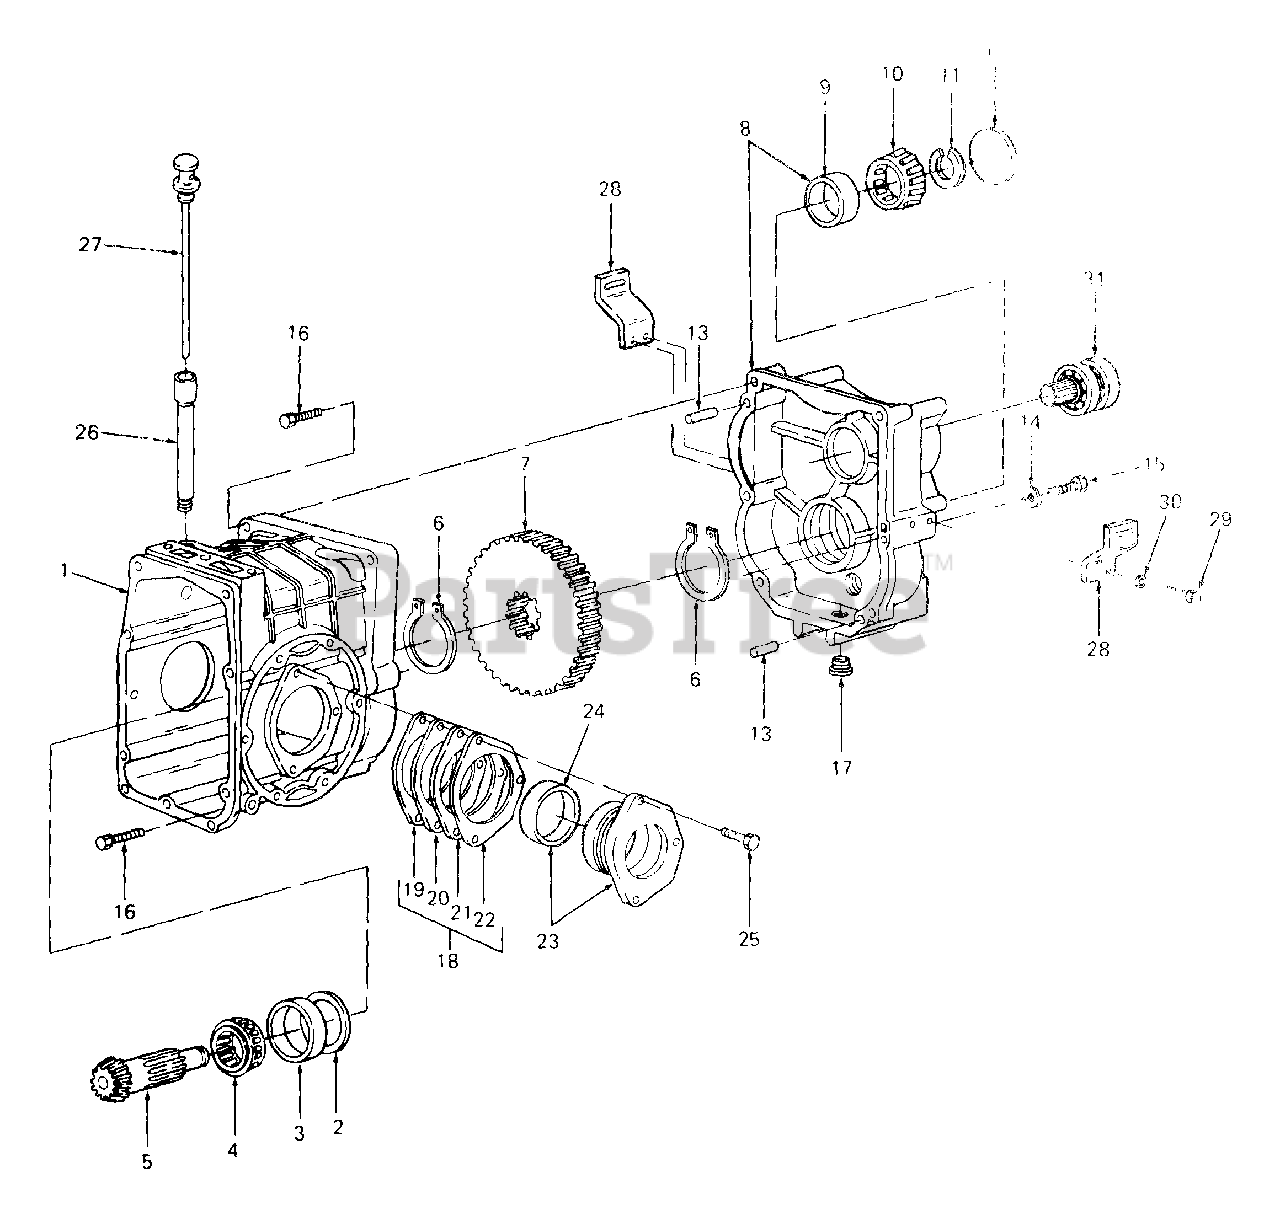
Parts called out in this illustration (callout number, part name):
1	Housing Assy, Rear Transaxle
2	Shim, Rear Bearing Cup, .004 Thk
3	Cup, Roller Bearing
4	Cone, Roller Bearing
5	Shaft, Bevel Pinion
6	Ring, Retaining, 1.312 Dia
7	Gear, Reduction - 71T
8	Adapter Housing Assy
9	Cup, Roller Bearing
10	Cone, Roller Bearing
11	Retainer, Front Bearing, .125 Thk
12	Plug, Expansion, 2.12 OD
13	Pin, Dowel, 3/8 Dia X 5/8 Lg
14	Washer, Spring, .445 X .75 X .017 Thk
15	Screw, Hex Cap, 7/16-14 X 2.75 Lg GR5
16	Bolt, Hex Patch, 7/16-14 X 1.75 Lg GR5
17	Plug, Drain Use Teflon Sealing Tape
18	Shim Package
19	Shim, Bearing Retainer, .004 Thk
20	Shim, Bearing Retainer, .007 Thk
21	Shim, Bearing Retainer, .014 Thk
22	Shim, Bearing Retainer, .028 Thk
23	Retainer Assy, Bearing
24	Cup, Roller Bearing
25	Bolt, Hex Patch, 3/8-16 X 1.0 Lg GR5
26	Tube, Dipstick Use Teflon Sealing Tape
27	Blade Assy, Dipstick
29	Screw, Hex Cap, 3/8-16 X 1.0 Lg GR8
30	Washer, Lock, 3/8
31	Pinion Assy, Input
